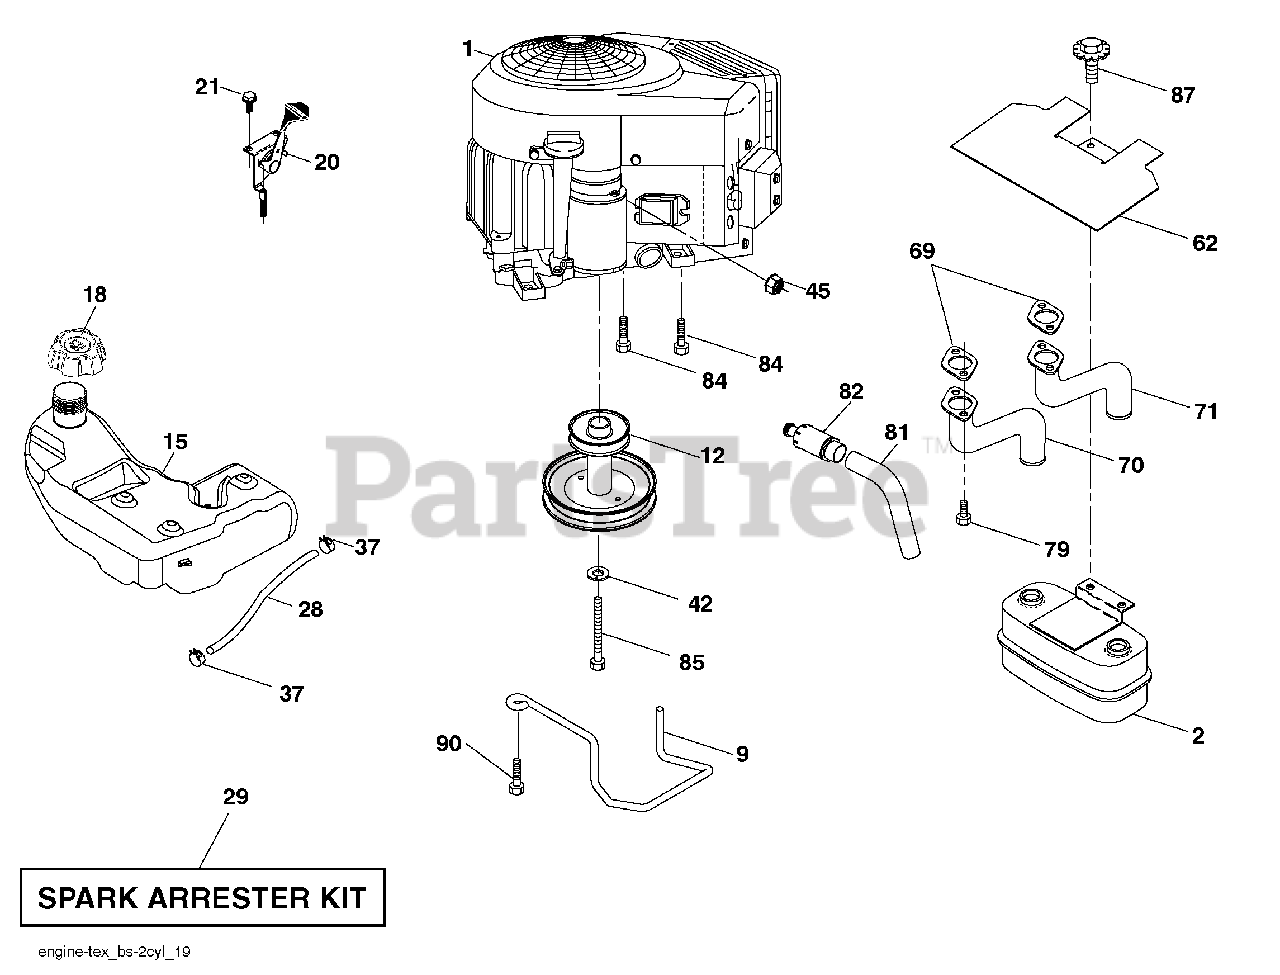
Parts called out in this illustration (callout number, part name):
2	Muffler
9	Keeper Belt Engine
12	Pulley Engine
15	Tank Fuel 3.0
18	Cap Asm
20	Control Throttle
21	Screw #10 x 0.750 BOS Thread
28	Fuel Line
29	Spark Arrester Kit
37	Clamp Hose
42	Washer Lock 7/16
45	Nut Keps Hex 1/4-20 unc
62	Shield Heat Muffler
69	Gasket
70	Exhaust Tube RH
71	Exhaust Tube LH
79	Screw Socket Head 5/16-18 x 1
81	Tube Drain Oil Easy
82	Plug Drain Oil
84	Screw 3/8-16 x 1-1/4
85	Bolt Hex 7/16-20 x 4 x 5 Ga.-1.5
87	Bolt 5/16-18 x 3/4
90	Screw 3/8-16 x 1
